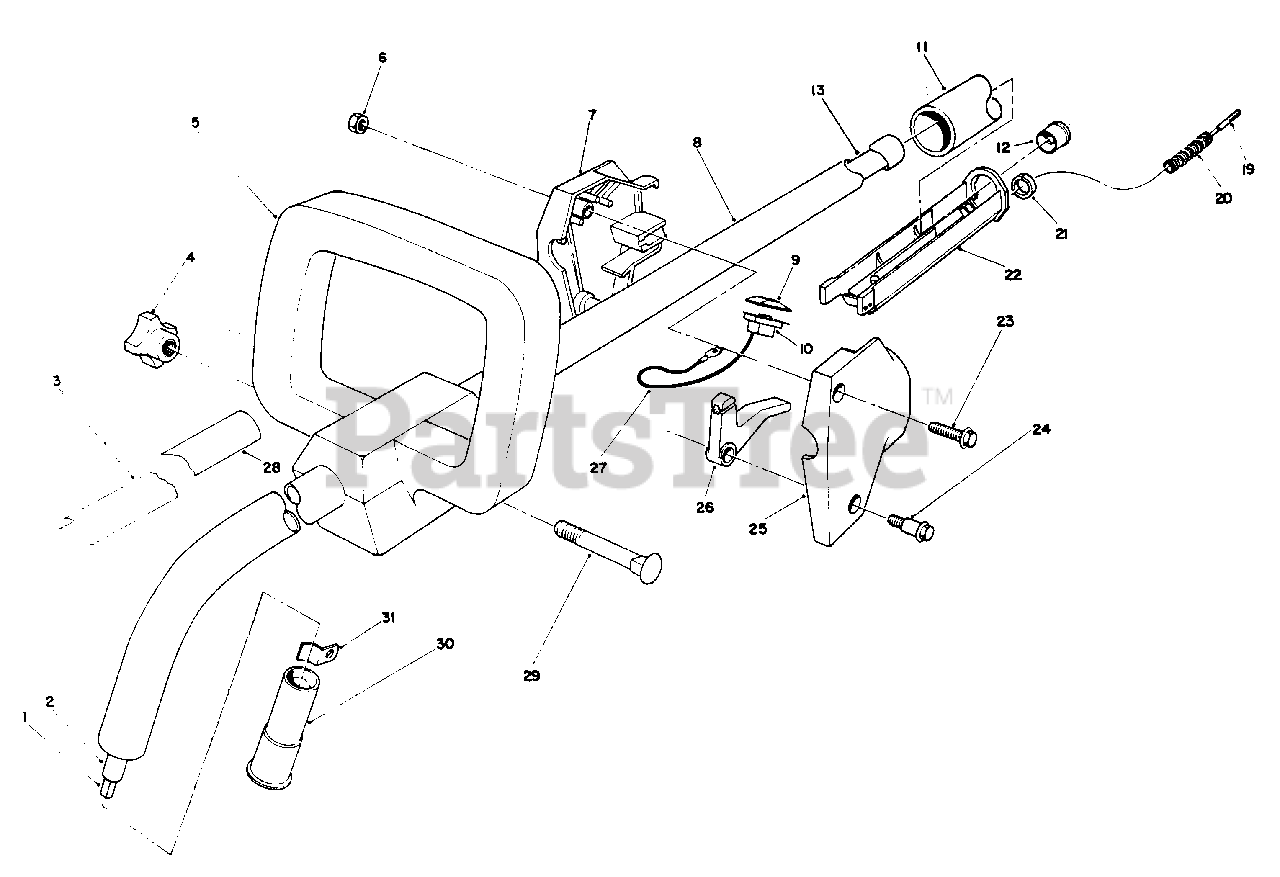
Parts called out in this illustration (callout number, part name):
1	Shaft-Flex Drive
2	Liner-Flex Shaft
3	Decal-Toro
4	Knob-Loop Handle
6	Nut-Lock
7	Housing-R.H.
8	Tube-Curved
9	Cap-Switch
12	Bushing-Pilot
19	Cable-Throttle
20	Cover-Cable
23	Screw-Hex. Washer Hd.
24	Screw-Shoulder
25	Housing-L.H.
26	Lever-Throttle
27	Wire Assembly
28	Decal-Warning
29	Bolt-Carriage
30	Insert-Pole End
31	Retainer-Tube
